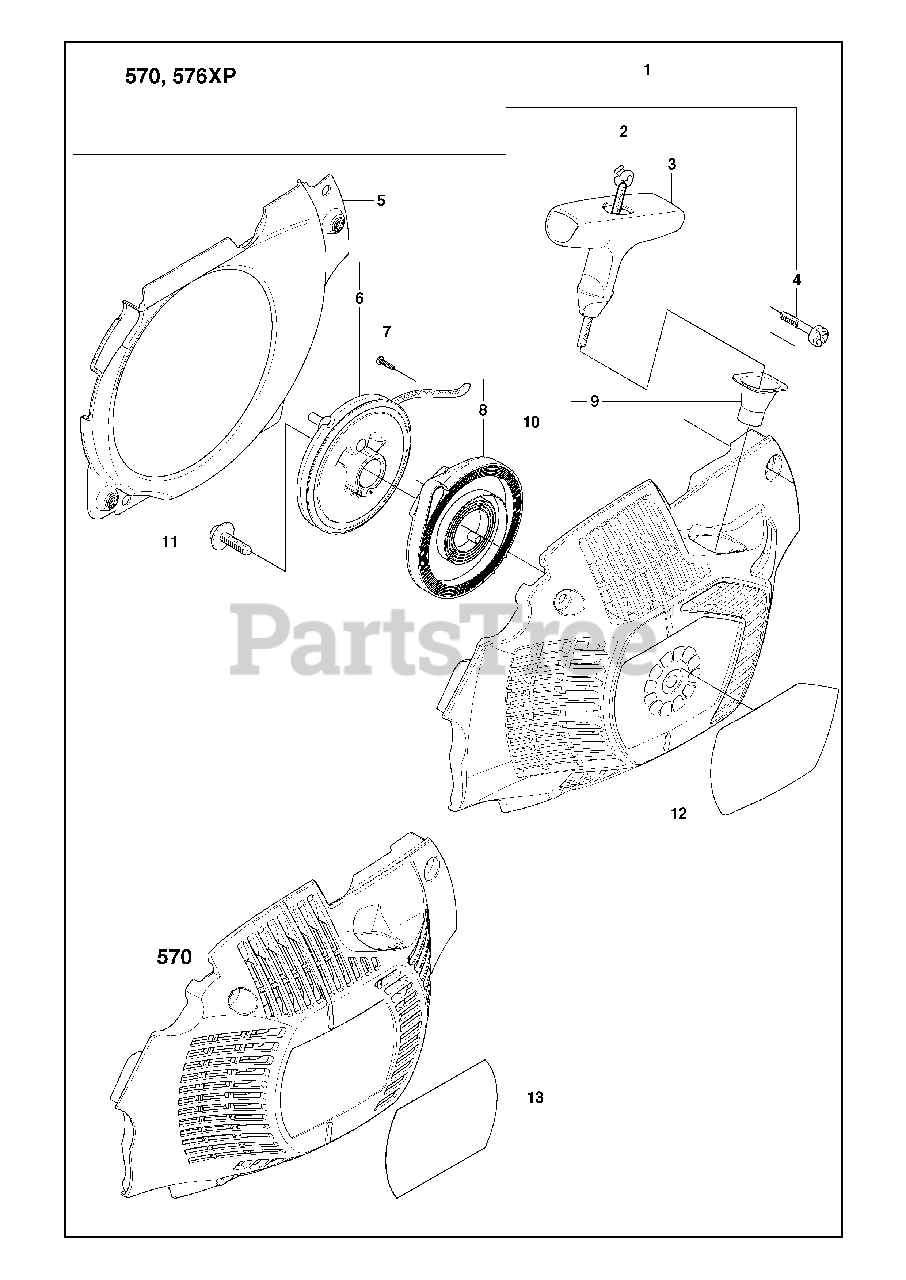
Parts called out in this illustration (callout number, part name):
1	STARTER ASSY
1	STARTER ASSY COMPLETE
2	STARTER ROPE
6	STARTER PULLEY
8	RP SPRING
10	STARTER HOUSING
10	STARTER COVER
12	LABEL
13	%DECAL
